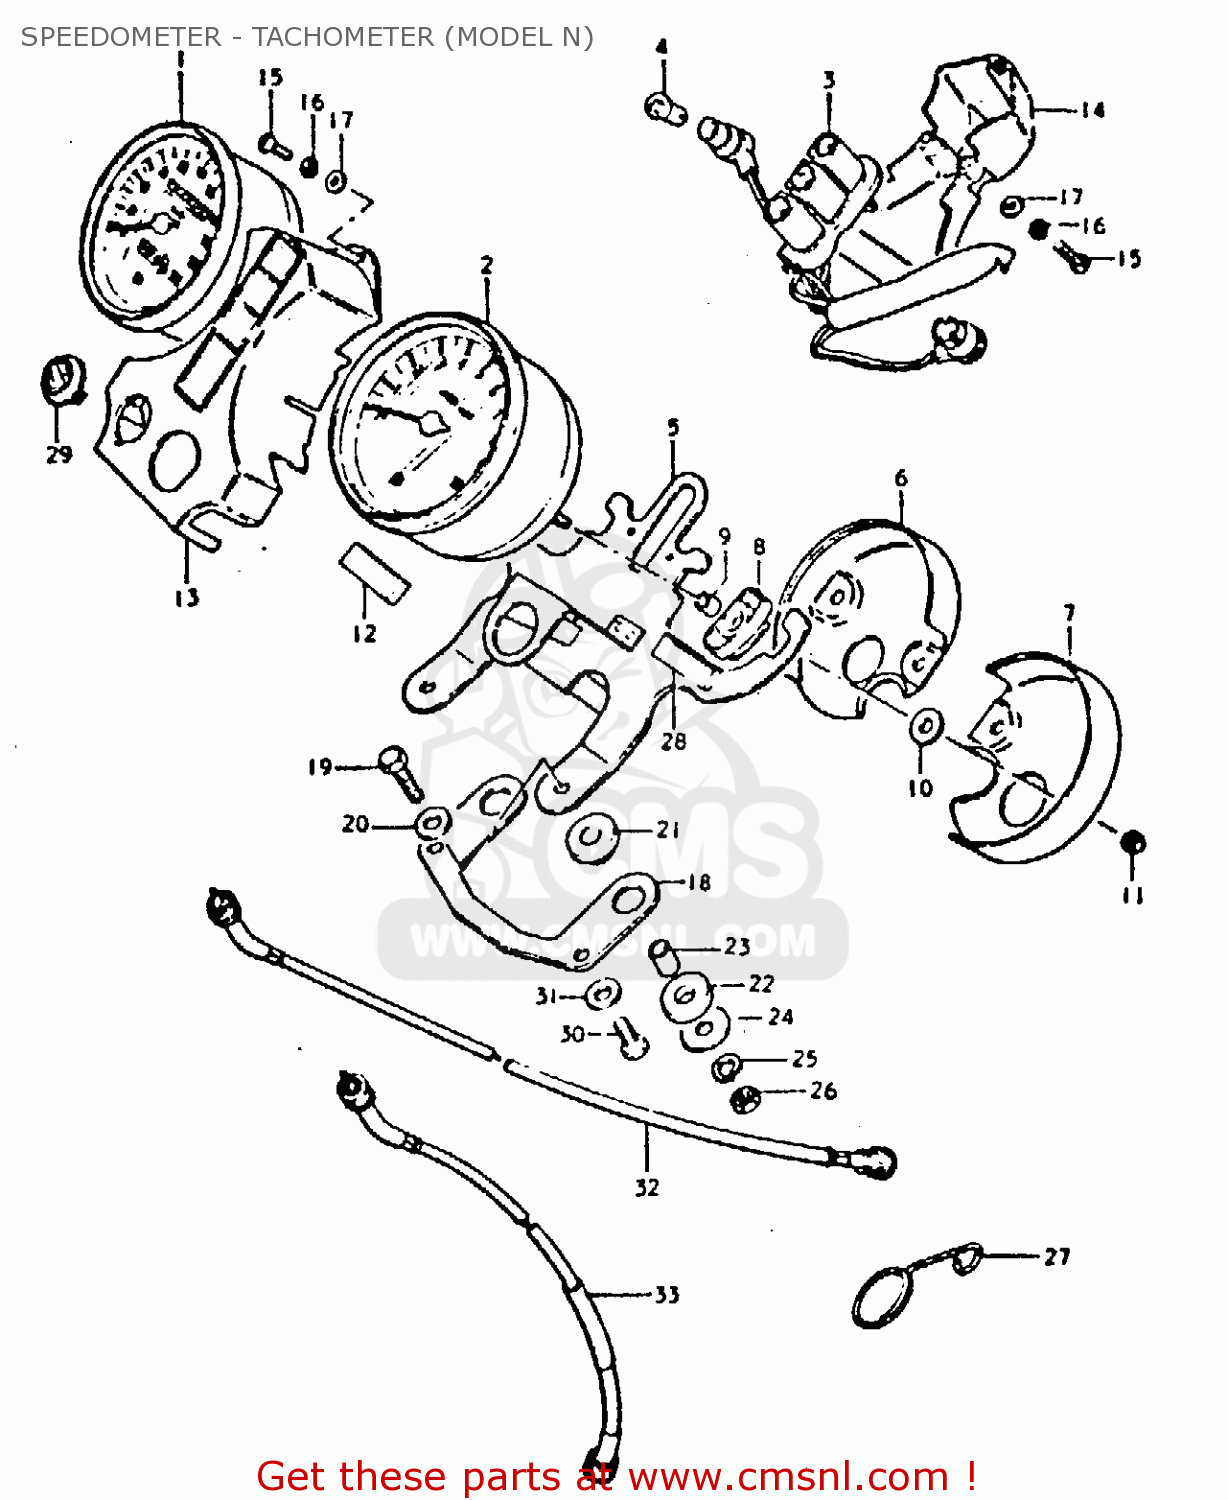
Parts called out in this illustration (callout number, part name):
1	SPEEDOMETER ASSY
2	TACHOMETER ASSY
3	SOCKET
4	BULB(12V3.4W,STANLEY,A72A)
5	BRACKET
6	UNDER COVER,SPEEDOMETER
7	UNDER COVER,TACHOMETER
8	CUSHION,METER
9	SPACER
10	WASHER (5.5X16X1.2)
11	NUT
12	CUSHION,METER
13	CASE, PILOT BULB
14	COVER
15	SCREW(4X16)
16	WASHER,PILOT UNDER CASE
17	WASHER
18	BRACKET
19	BOLT
20	WASHER
21	CUSHION
22	CUSHION
23	SPACER
24	WASHER (6.5X24X1.6)
25	LOCK WASHER
26	NUT
27	CLIP,TACHOMETER CABLE
28	PAD
29	CAP,SPEED WARNER LAMP HOLE
30	BOLT, UPPER
31	WASHER
32	CABLE, SPEEDOMETER
33	CABLE, TACHOMETER
